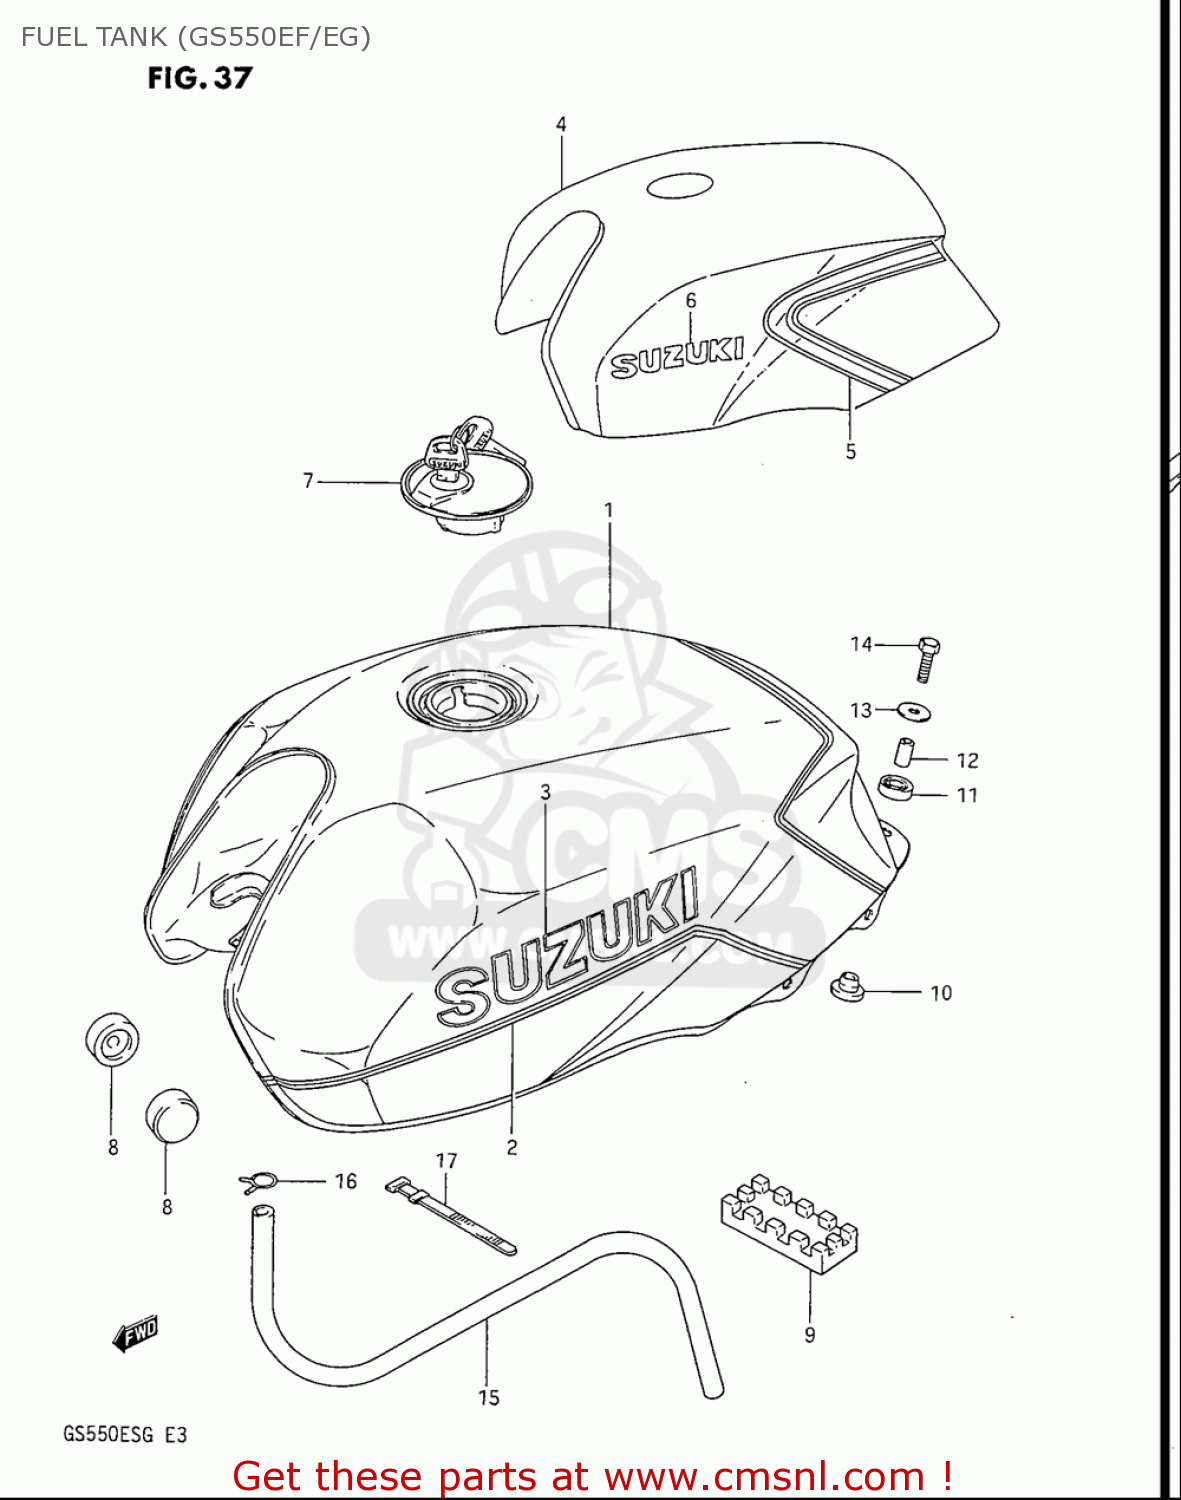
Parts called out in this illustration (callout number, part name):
1	TANK ASSEMBLY,FUEL
3	EMBLEM
6	EMBLEM
7	CAP SET,FUEL TANK
8	CUSHION
10	CUSHION
11	CUSHION
12	SPACER(6.5X9X20)
13	WASHER(6.5X24X1.6)
14	BOLT
15	HOSE(5X8.2X2000)
16	CLIP
17	CLAMP(L:187)
